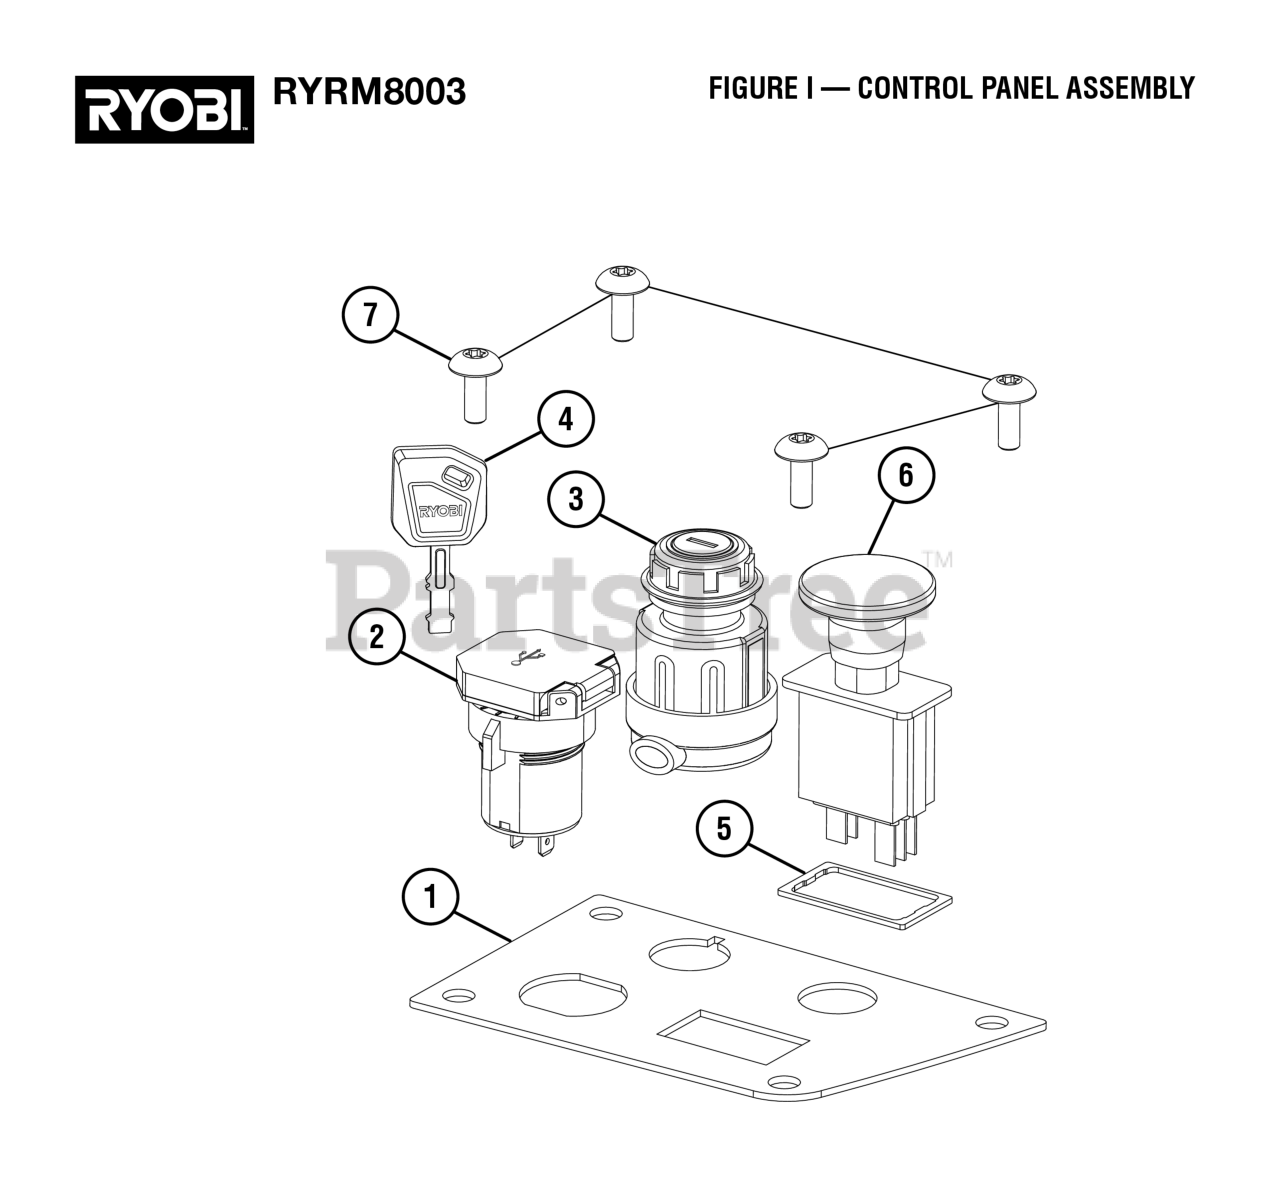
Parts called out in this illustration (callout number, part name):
1	Control Panel Plate
2	USB Module
3	Key Module
5	PTO Gasket
6	Power Take Off (PTO) Button
7	Screw (M6 x 10 mm, Soc. Button Hd.)
